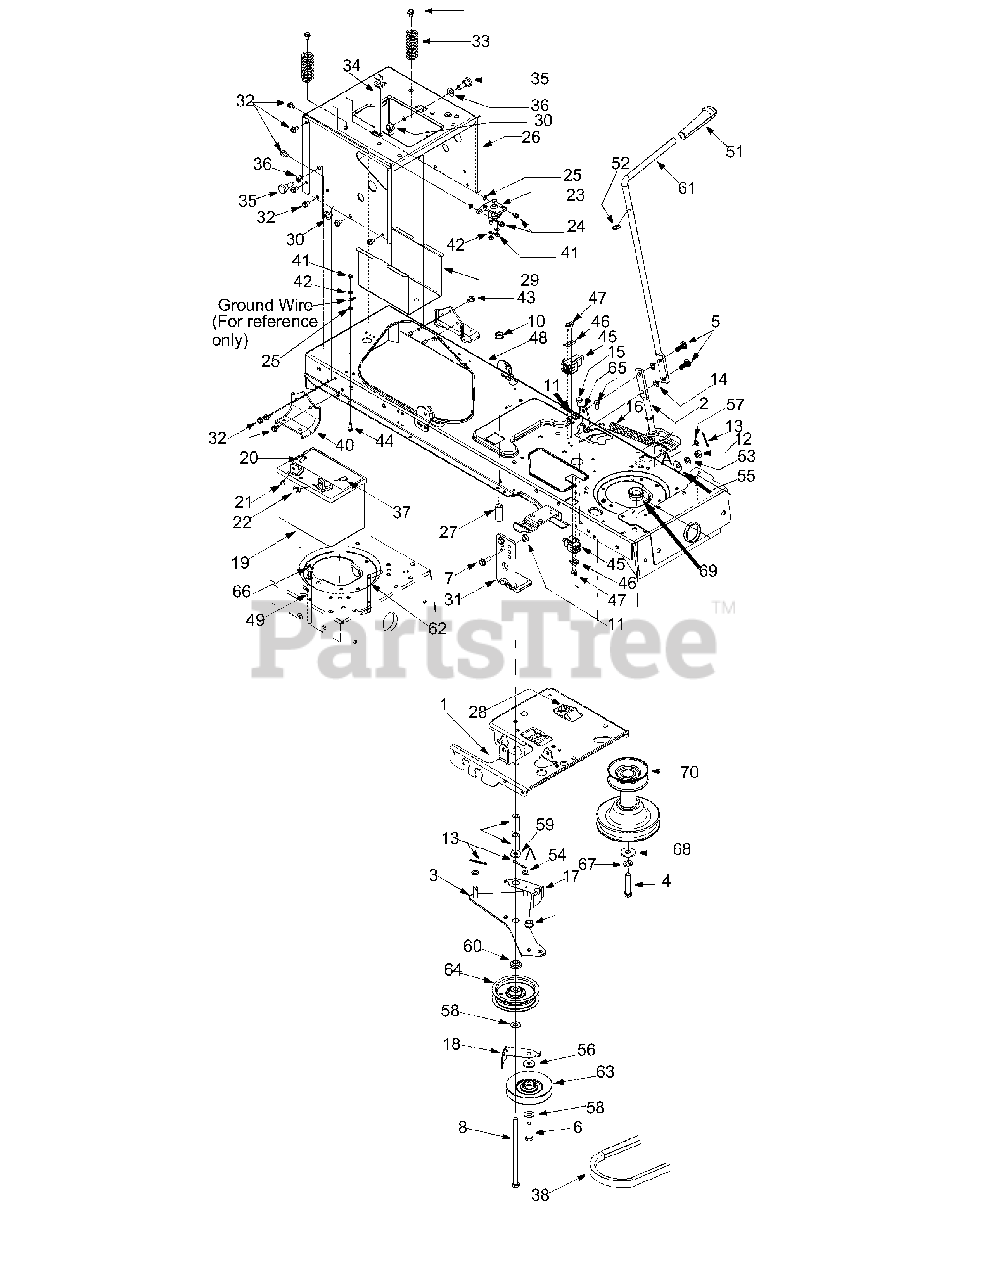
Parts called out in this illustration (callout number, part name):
1	Steering Support Bracket
2	PTO Lever Engagement Assembly
3	Engagement Plate Assembly
4	Hex Bolt 7/16-20 x 2.0
5	Carriage Screw 5/16-18 x 1.0
6	Hex Screw 3/8-16 x 1.5
7	AB Screw, 5/16-12 x .75
8	Hex Screw 3/8-16 x 7.0
10	Flange Lock Nut
11	Flange Lock Nut
12	Hex Nut
13	Cotter Pin
14	Speed Nut
15	Hex Cap Screw 5/16-18 x .625
16	Extension Spring
17	Belt Guard
18	Belt Guard
19	12 V Battery
20	Hex Cap Screw, 1/4-20 x .62
21	Hex Sems Nut, 1/4-20
22	Wing Nut, 1/4-20
23	Solenoid, 12-Volt, 100 Amp
24	Self Tapping Screw, 1/4-20 x .5
25	Lock Washer, 1/4
28	Hex Split Flange Bearing
32	Self Tapping Screw, 5/16-18 x .625
33	Compression Spring, 1.28 x 3.5
34	Battery Strap
35	Shoulder Screw, .625 x .5, 7/16-20
36	Bell Washer, .45 x 1.0 x .062
37	Shoulder Screw
38	PTO Belt
41	Hex Nut 1/4-20
42	Lock Washer
43	TT Screw 5/16-18 x 0.5
44	TT Screw 1/4-20 x 0.75
45	Switch
46	Switch Plate
47	AB Screw #10-16 x 0.5
50	Push Nut Retainer
51	PTO Knob
52	Flat Washer
53	Lock Washer
54	Flat Washer
55	Bell Washer
56	Flat Washer
57	Flat Washer
58	Flat Washer
59	Flat Washer
60	Shoulder Spacer
61	Deck Engagement Handle
62	Belt Keeper Rod
63	Idler Pulley
64	Idler Pulley
66	Lock Washer
67	Lock Washer
68	Flat Washer
69	Spacer
70	Engine Pulley
